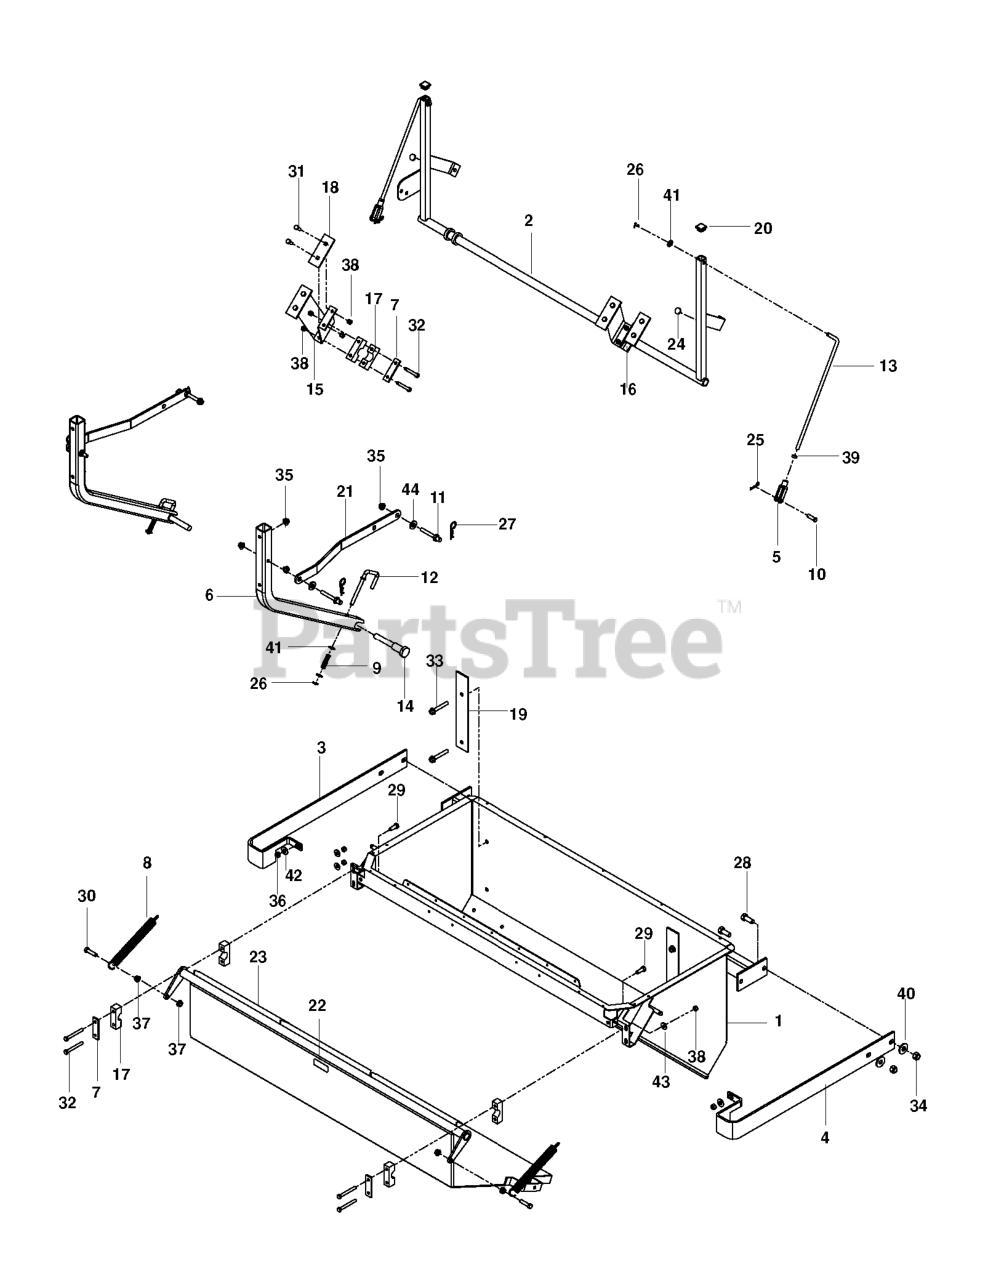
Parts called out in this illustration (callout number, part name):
1	PLATE, BLK
2	PLATE.MOUNTING.PNT
3	HOPPER WLDT BLK
4	BELLCRANK.WELDMENT
5	GUARD - L.H.
6	GUARD - R.H.
7	YOKE-3/8-24 PLTD
8	TUBE.HITCH.BLK
9	REINFORCEMENT BAR
10	SPRING BAGGER
11	SPRING, COMPRESSION
12	PIN CLEVIS, 3/8 X 1 1/4
13	ROD.DOOR.COLECTION
15	COTTER PIN
16	HAIRPIN #2
17	HAIRPIN #4
18	ROD.DOOR.COLECTION
19	BOLT, PIVOT
20	BRACKET, SUPPORT LEFT BLK
21	BRACKET, SUPPORT RIGHT BLK
22	GROMMET, BUMPER
23	PILLOW BLOCK
24	PLUG - SQUARE TUBE
25	STRAP BLACK
26	DECAL, VENTILATION
27	WELDMENT - DOOR
28	HCS 1/2-13 X 1-1/4
29	HCS 3/8-16X1.GRD.5.ZD
30	HCS 3/8C X 1 1/2
31	SCREW 5/16C X 1 HEX CAP
32	HCS 5/16C X 2-3/4
33	HHFS 3/8-16 X 2.5 GR 5 ZD
34	NUT 1/2-13 HEX NYLOC ZD
35	NUT 3/8-16 HEX FLG NYLOC ZD
36	NUT 3/8-16 NYLOC
37	NUT 3/8C WHIZ
38	NUT.71038.31-18.HEX.NYLOCK
39	NUT 3/8-24 JAM
40	WASH USS FLAT 1/2
41	WASHER 3/8 SAE FLAT
42	WASHER 3/8 FLAT
43	WASHER 5/16 FLAT
44	WASHER STEEL
